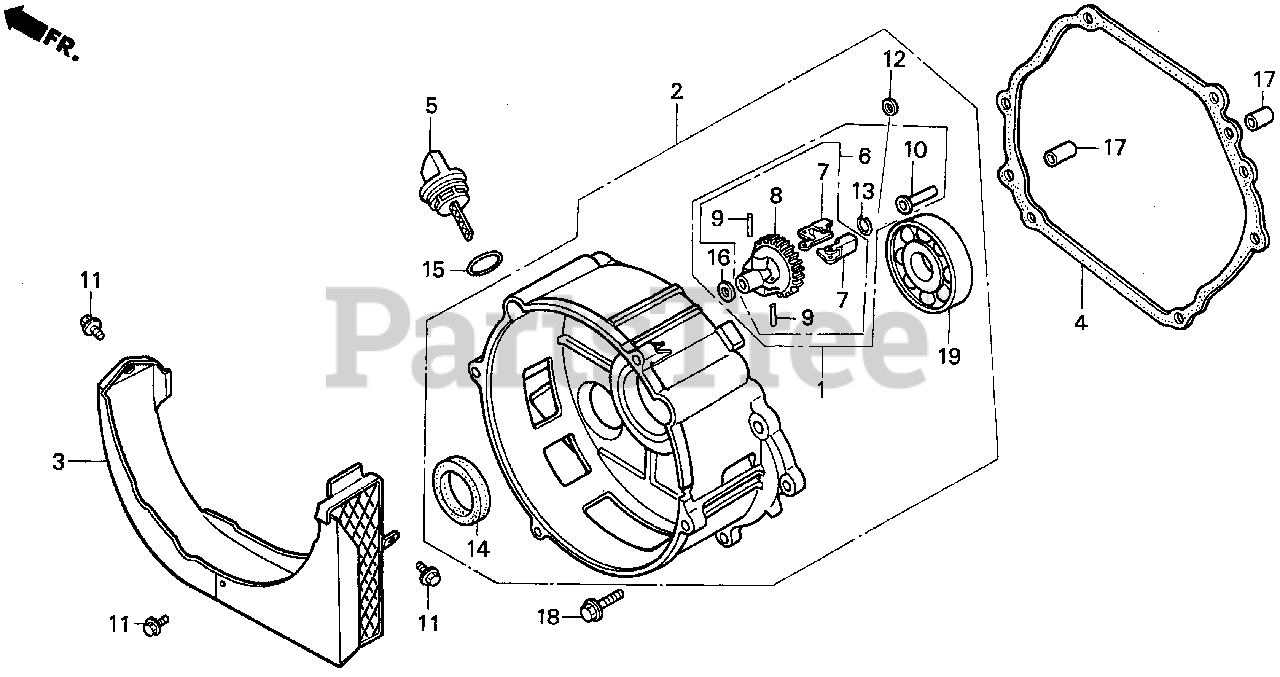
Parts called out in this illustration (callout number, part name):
1	GOVERNOR KIT (STD)
1	GOVERNOR KIT (BALANCER) (Honda Code 3313665). (NOT AVAILABLE)
2	COVER ASSY., CRANKCASE
3	COVER, DUCT
4	GASKET, CASE COVER
5	CAP, OIL FILLER
6	GOVERNOR ASSY. (STD)
7	WEIGHT, GOVERNOR
8	HOLDER, GOVERNOR WEIGHT
9	PIN, GOVERNOR WEIGHT
10	SLIDER, GOVERNOR
11	BOLT, FLANGE (5X10)
12	WASHER (6X16)
13	CLIP, GOVERNOR HOLDER
14	OIL SEAL (30X46X8)
15	O-RING (26X2.7)
16	WASHER, PLAIN (6MM)
17	PIN A, DOWEL (8X12)
17	PIN A, DOWEL (8X14)
17	PIN, DOWEL (8X12)
18	BOLT, FLANGE (8X35)
19	BEARING, RADIAL BALL (6206)
